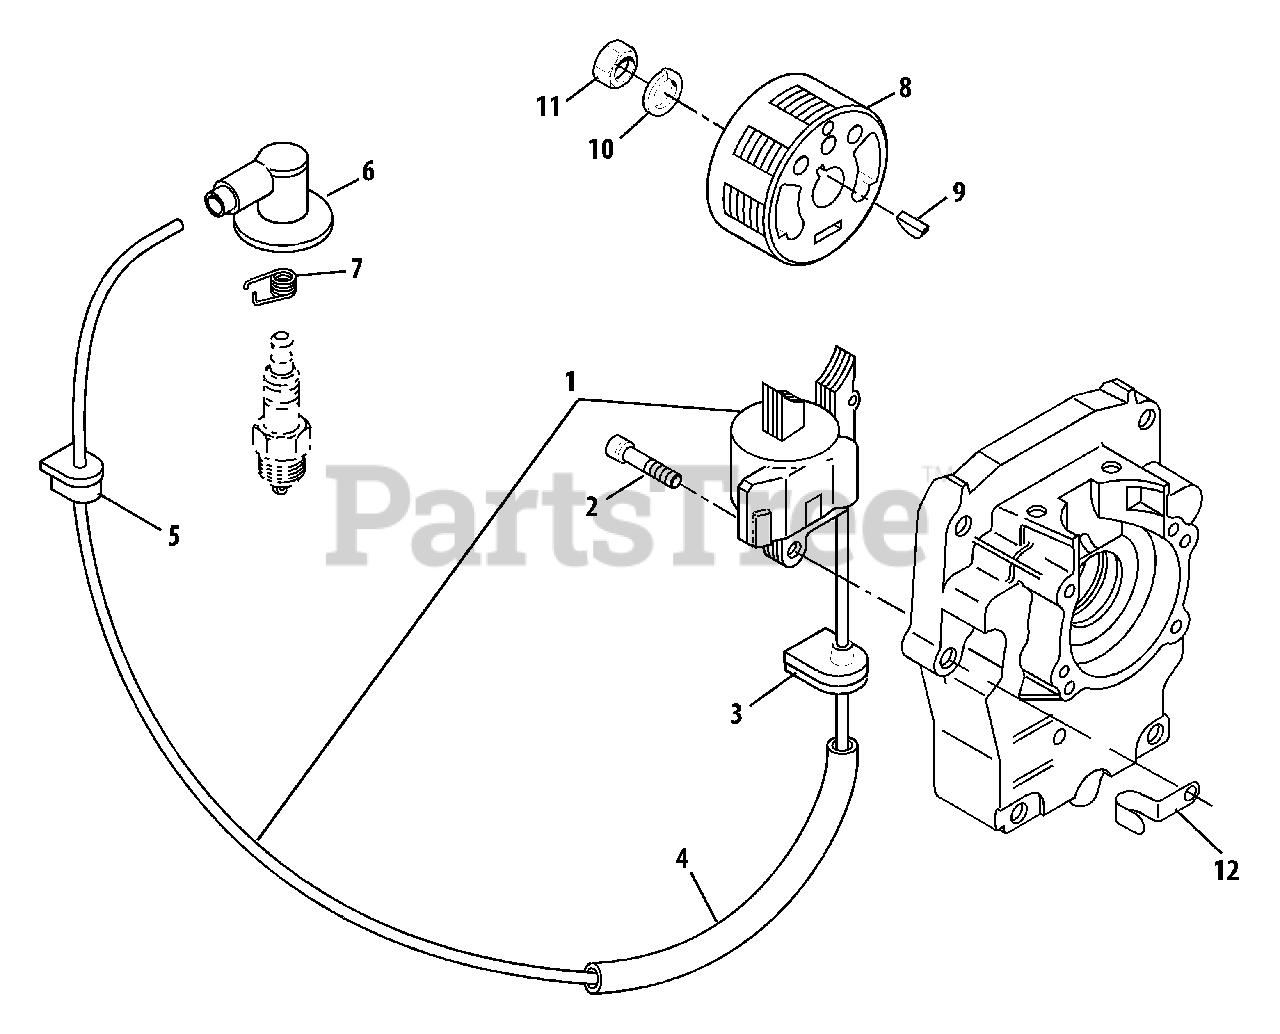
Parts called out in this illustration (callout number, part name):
1	COIL
2	SCREW - 5X20
3	GROMMET
4	TUBE
5	GROMMET
6	CAP, SPARK PLUG
7	TERMINAL, SPARK PLUG CAP
8	FLYWHEEL
9	KEY - 3X10
10	LOCKWASHER - 10
11	NUT - 10
12	CLIP, WIRE
